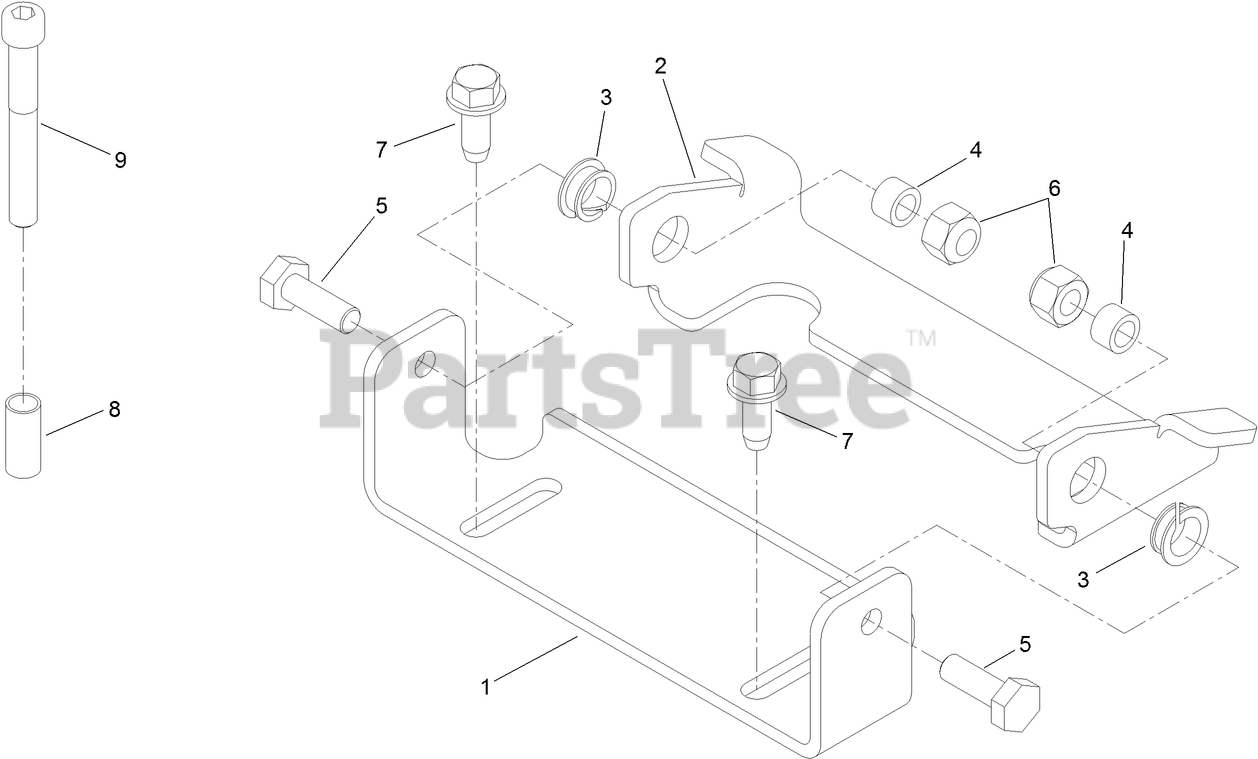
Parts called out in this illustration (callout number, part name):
1	BRACKET-LEVER LOCK
2	ARM-LEVER LOCK
3	BUSHING-NYLINER
4	SPACER
5	SCREW-HH
6	NUT-LOCK, NI
7	SCREW-HWH
8	SPACER
9	SCREW-HSH
